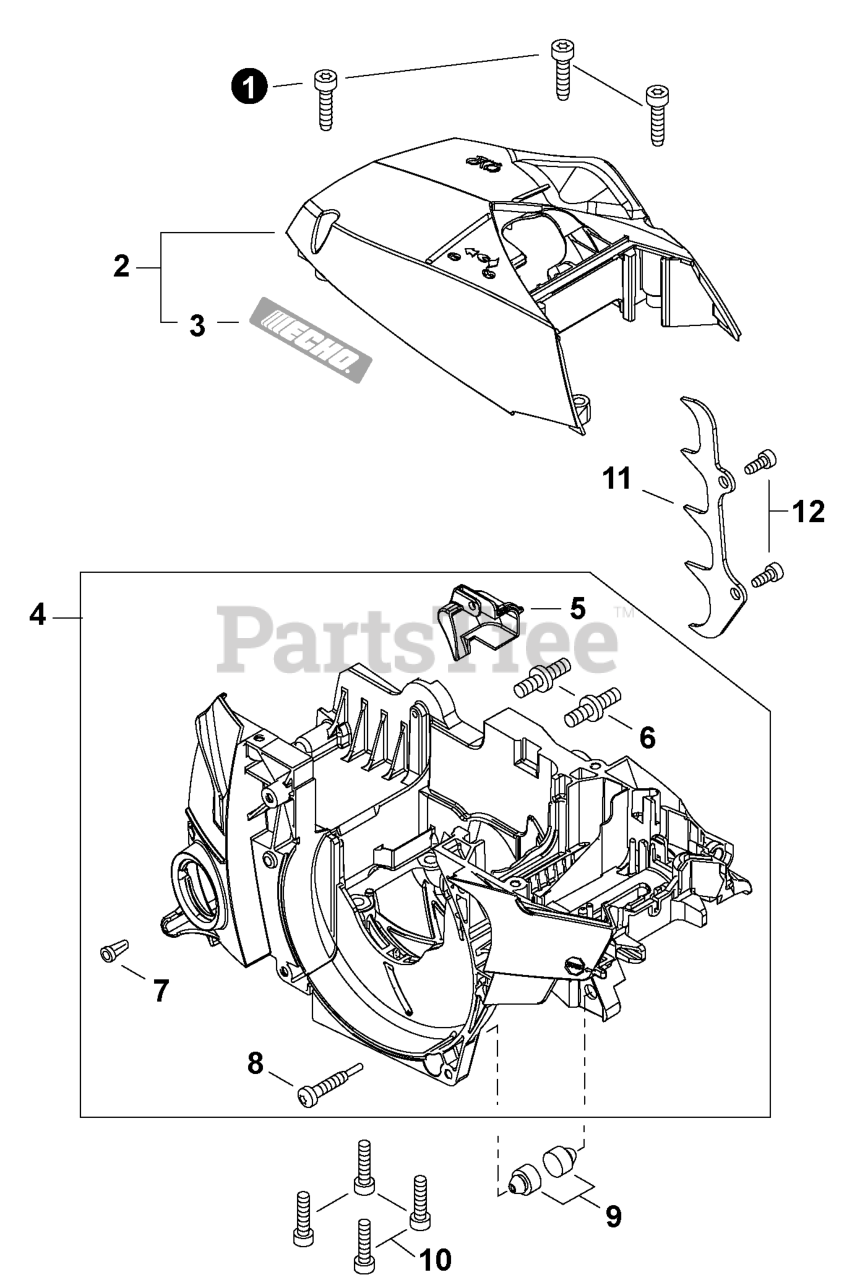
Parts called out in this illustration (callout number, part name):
1	BOLT, TORX 5x20
2	COVER, ENGINE
3	LABEL - ECHO
4	HOUSING ASSY, ENGINE
5	DUCT, AIR
6	BOLT, STUD 8
7	VENT ASSY
9	CUSHION
10	BOLT 5x40
11	SPIKE, BUMPER
12	BOLT, TORX 5x20
